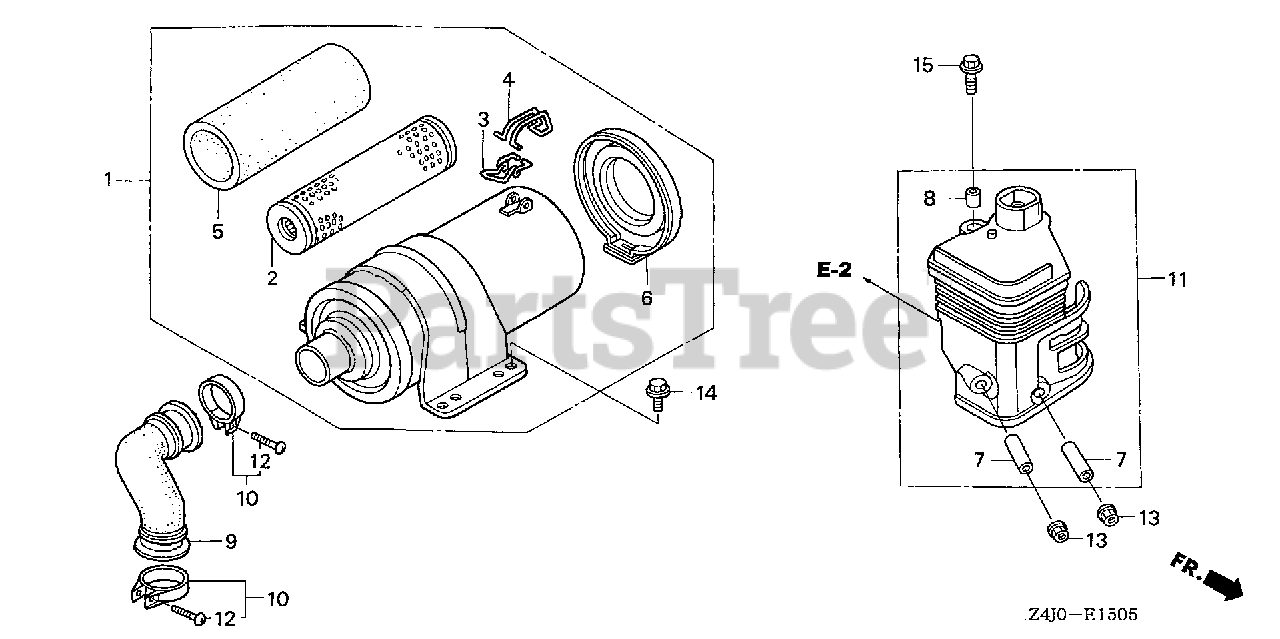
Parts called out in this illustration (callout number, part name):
1	AIR CLEANER ASSY.
2	ELEMENT, AIR CLEANER
3	CLIP A, WIRE
4	CLIP B, WIRE
5	FILTER (OUTER)
6	COVER, AIR CLEANER
7	COLLAR, AIR CLEANER
8	COLLAR B, AIR CLEANER
9	TUBE, AIR CLEANER CONNECTING
10	BAND, AIR CLEANER CONNECTING TUBE
11	ELBOW, AIR CLEANER
12	SCREW, PAN (4X20)
13	NUT, FLANGE (6MM)
14	BOLT, FLANGE (6X16)
15	BOLT, FLANGE (6X20)
